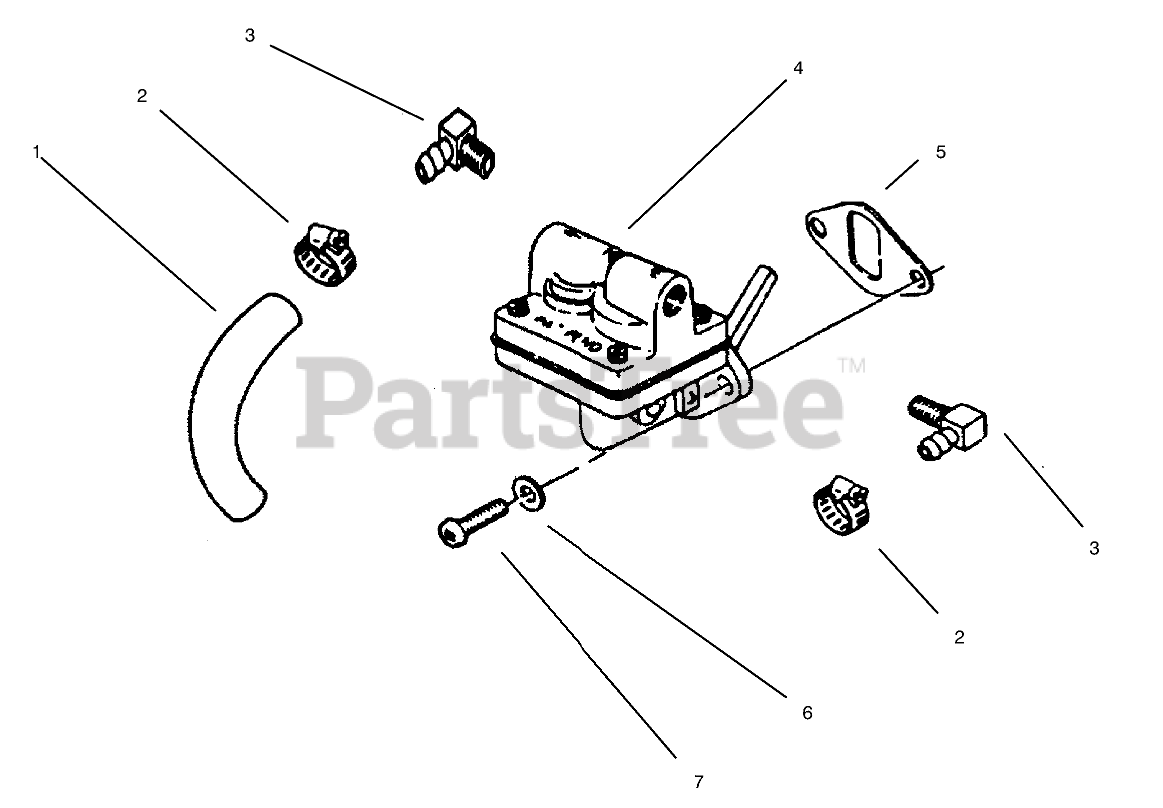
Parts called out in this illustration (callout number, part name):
1	Line-Fuel
2	Clamp
3	Connector-90deg.
4	Pump ASM-Fuel INC 5&7
6	Washer
7	Screw-F.H.
